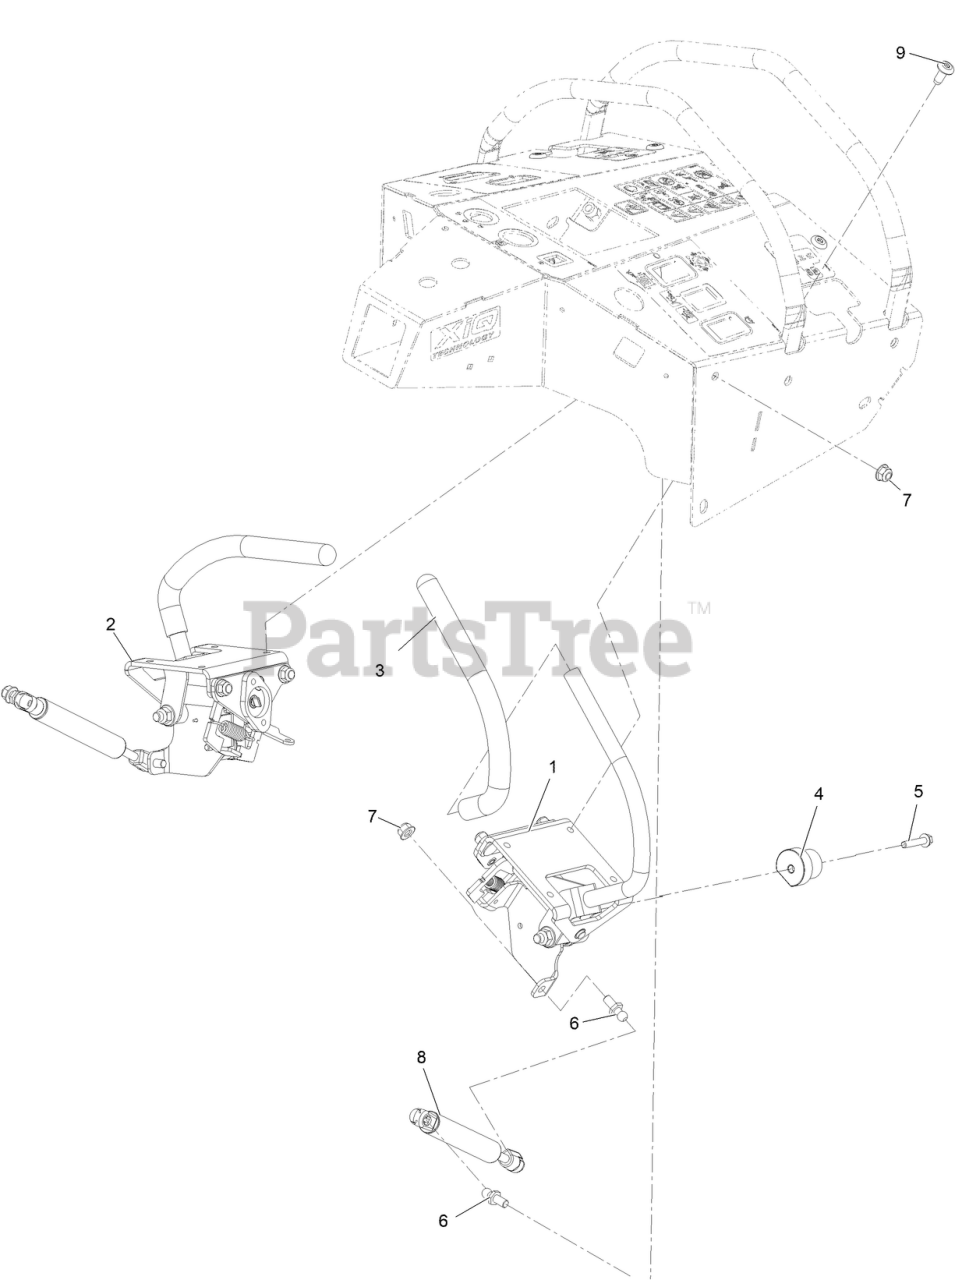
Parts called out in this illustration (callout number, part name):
1	CONTROL HANDLE ASM, LH
2	CONTROL HANDLE ASM, RH
5	SCREW-HWH
6	STUD-BALL
7	NUT-HF, NI
8	DAMPER, MOTION CONTROL
